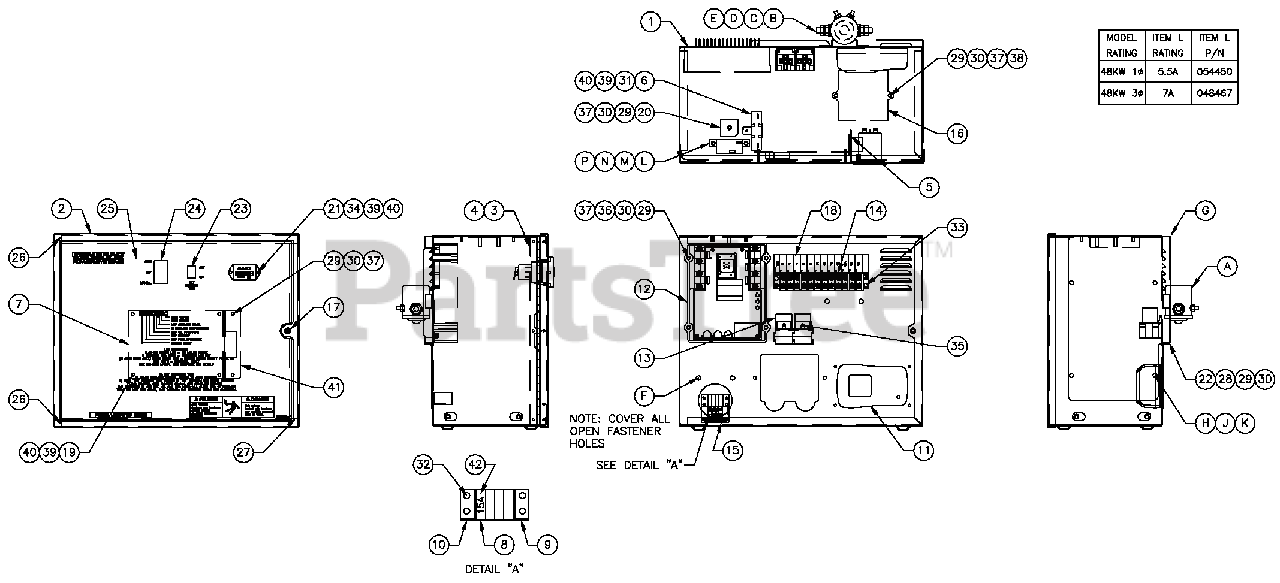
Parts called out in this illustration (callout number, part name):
1	ENCLHSBCONTROL PANEL
2	COVER CONTROL PANEL R-200B
3	HINGE CONTINUOUS H-PANEL
4	RIVET POP .125 X .275 SS
5	SCREWPPPH HI-LO#4-24X3/8
6	WASHER FLAT M3
7	ASSY PCB R200B CNTRL 1800 RPM
8	HOLDERFUSEWICKMANN 178.6150
9	ADPTR RH SIDE WICKMANN 178.6191
10	ADPTR LH SIDE WICKM ANN 178.6192
11	BATC 13.4VDC 2.5A W/4POS PLUG
12	ASSY PCB HI-PWR VOLTAGE RGLTR
13	RELAY 12VDCC FORMW/DIODE
14	BLOCK TERM 20A 12X 6X1100V
15	DECAL CPLCNTPNL FUSES
16	ASSY PCB BOSCH GOV DRIVER
17	M5X0.8 CAPTIVE PANEL KNLD HD
18	DECAL CPL3.9LTB1
19	SPACER 9.5H 32 ID
20	DIO BRIDGE 25A 600V
21	HOUR METER 10-80VDC
22	PLATE HARNESS CLAMP
23	SWITCH RKRDPST 125V SPD
24	SWITCH RKR DPDT ON-OFF-ON
25	DECAL CONTROL FLEXR-200B
26	SEAL COVER 3.18X12.7X382
27	SEAL COVER 3.18X12.7X283
28	SCREW HHPMM5-0.8X 12
29	WASHER FLAT M5
30	WASHER LOCK M5
31	RES WW15R 5% 25W QK CONN
32	SCREW PHTTM3.5-0.6X10
33	SCREW PHTTM3.5-0.6X16
34	SCREWPHM M3-0.5X 10BLACK
35	SCREW PHTT M4-0.7 X10 ZYC
36	SCREW PPHMM5-0.8 X50ZNC
37	NUT HEXM5-0.8G8 YEL CHR
38	SCREW PPHM M5-0.8 X30SS
39	WASHER LOCK M3
40	NUT HEXM3-0.5G8 YEL CHR
41	SUPPORT ANGLE PCB
42	FUSE ATO TYPE 15 AMP (BLUE)
A	RELAY SOLENOID 12VDCPNLMNT
B	SCREW HHC1/4-20X3/4 G5
C	WASHER FLAT 1/4-M6ZINC
D	WASHER LOCK M6-1/4
E	NUT HEX 1/4-20STEEL
F	SEAL WEATHER .45"DIA
G	COVER CONTROL PANEL SIDE
H	SCREW PPHM M5-0.8 X12ZNC
J	WASHER LOCK M5
K	WASHER FLAT M5
L	DPE BREAKER
M	WASHER FLAT M3
N	WASHER LOCK M3
P	NUT HEXM3-0.5G8 YEL CHR
